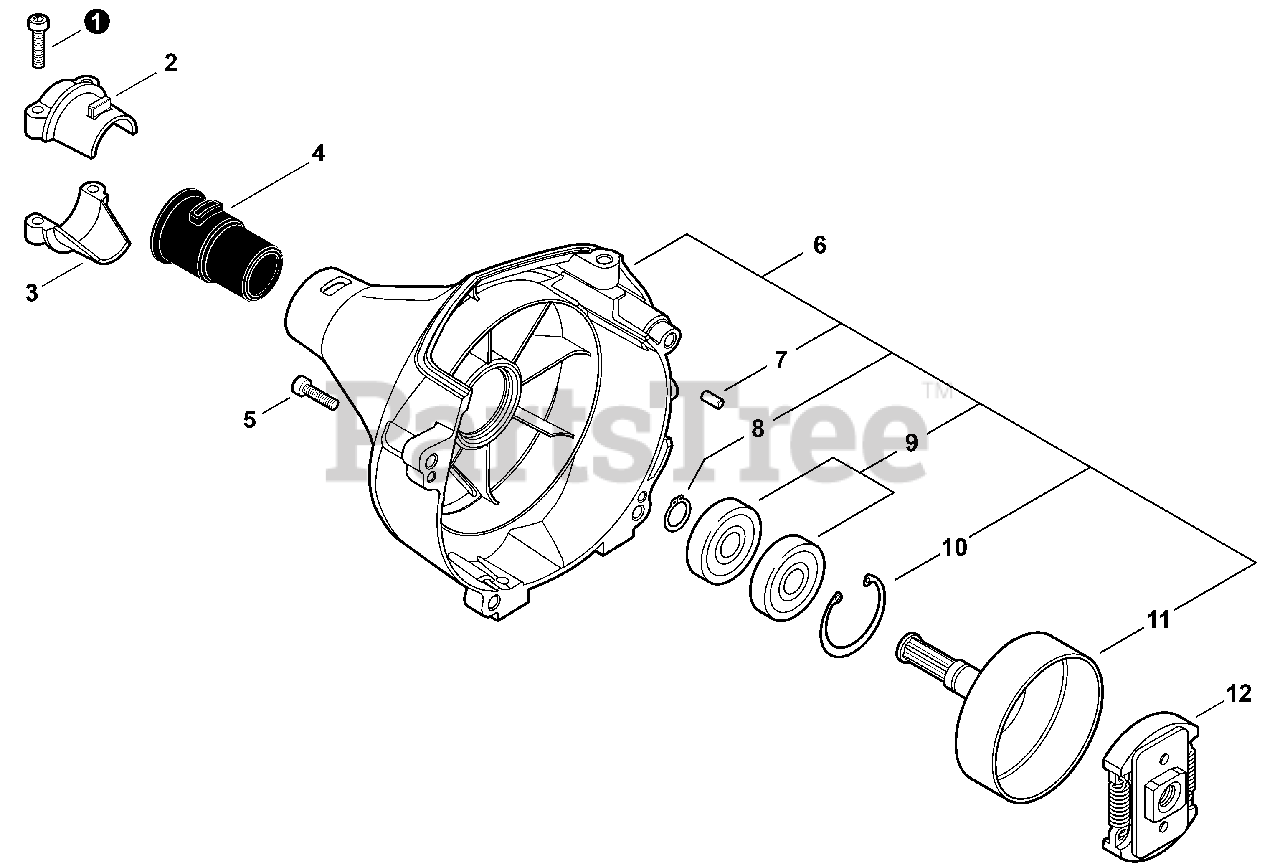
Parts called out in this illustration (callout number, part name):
1	SCREW - 5×20
2	HOLDER, MAIN PIPE - UPPER
3	HOLDER, MAIN PIPE - LOWER
5	SCREW - 4×16
6	FAN CASE ASSY
7	PIN, LOCATING
8	RING, RETAINING - 12
9	BEARING, BALL - 6001
10	RING, RETAINING - 28
11	DRUM, CLUTCH
12	CLUTCH ASSY
